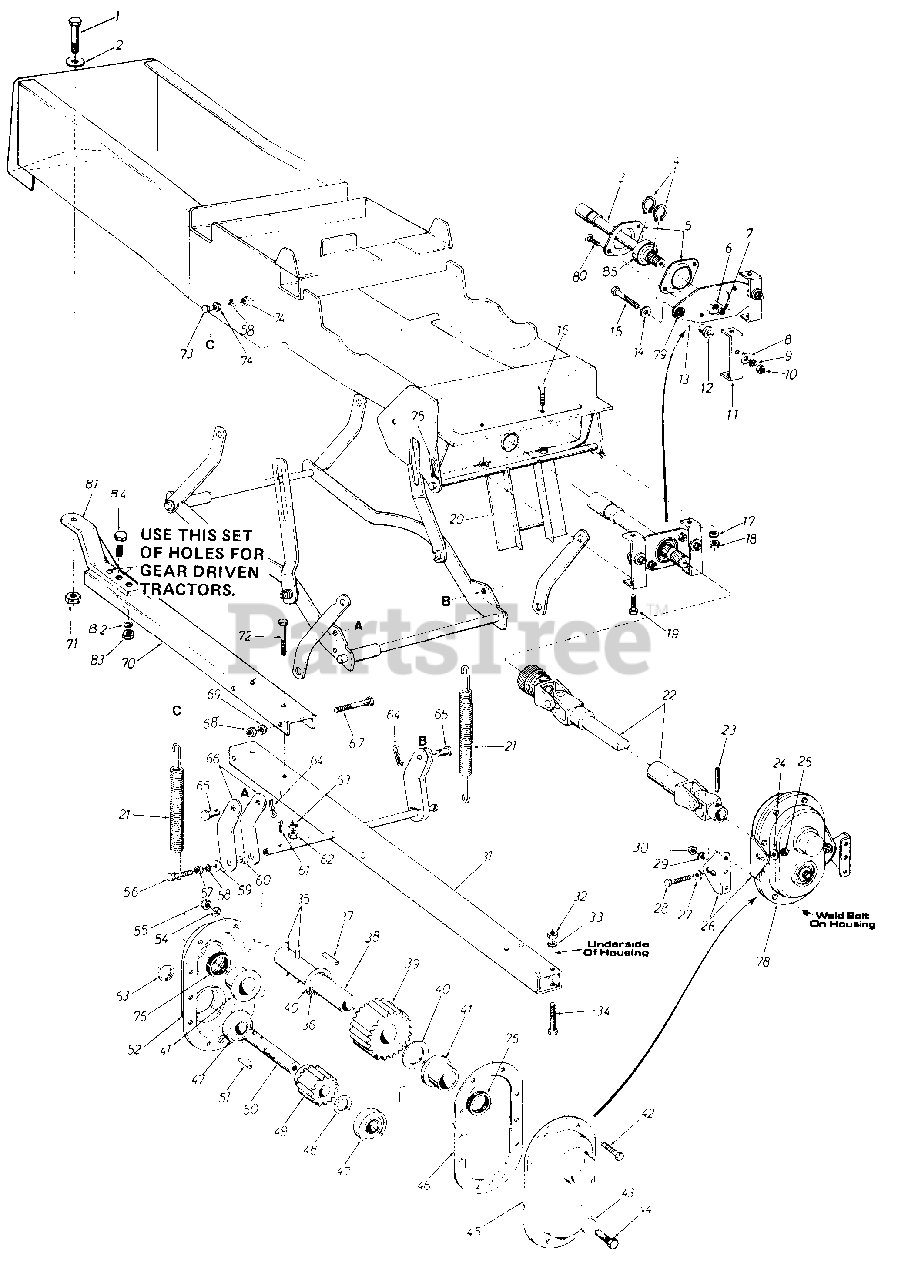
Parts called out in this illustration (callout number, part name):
1	Hex Scr. 5/8-18 x 1.31" Lg.
2	Fl.-Wash. .66" I.D. x 1.25" O.D. x .100
3	P.T.O. Shaft Extension Ass'y .
4	Retaining Riny 1.00" Dia. Shaft
5	Flangette Bearing
6	L.-Wash. 5/16" Scr.*
7	Hex Nut 5/16-18 Thd.*
8	Fl.-Wash. 3/8" I.D. x 1.00"O.D.
9	L Wash. 3/8" Scr.*
10	Hex Nut 3/8-24 Thd.*
11	P.T.O. Bearing Retaine Brkt.
12	Shoulder Spacer
13	P.T.O. Bearing Retainer Plate
14	Fl.-Wash. 3/8" I.D. x 1.00 O.D.
15	Hex Scr. 3/8-24 x 1.50" Lg.*
16	Hex Scr. 3/8-16 x .75" Lg.*
17	L.-Wash. 318" Scr.*
18	Hex Nut 3/8-16 Thd.*
19	Hex Scr. 3/8-16 x .75" Lg.*
20	Guide Bracket Ass'y.
21	Helper Spring .94 O.D. x 7.38" Lg.
22	Universal Drive Shaft Ass'y.
23	Spring Pin Spirol 5/16" x 2.50" Lg.
24	Belleville Wash. .341 I.D. x .88 O.D.
25	Hex Nut 5/16-18 Thd.*
26	Gear Box Support Bracket
27	Belleville Wash. .34 I.D. x .88 O.D.
28	Hex Scr. 5/16-18 x .75" L.g*
29	L.-Wash. 5/16" Scr.*
30	Hex Nut 5/16-18 Thd.*
31	Lift Shaft Ass'y.
32	Hex Ins. Jam L.-Nut 3/8-24 Thd.
33	L.-Wash. 3/8" Scr.*
34	Hex Scr. 3/8-24 x 2.75"Lg.*
35	Spring Pin Spirol 5/16" Dia. 1.75" Lg.
36	Snap Ring for 1.25" Dia. Shaft
37	Sq. Key 1/4" x 1.00" Lg.
38	Gear Shaft
39	28 Teeth Spur Gear
40	Fl.-Wash. 1.31" I.D. x 2.00"
41	Flange Bearing 1.25" I.D. 41.75" O.D.
42	Hex Screw 1/4-28 x .88 "Lg.
43	Fl.-Wash. .40" I.D. x 1.25" O.D. x .160
44	Hex L.-Scr. 3/8-24 x 1.00"Lg.
45	Complete Gear Housing Half-L.H.
46	Gasket
47	Ball Bearing 1.00" I.D. x 2.00" O.D.
48	Fl.-Wash. 1.03" I.D. x 1.63" O.D. x .090
49	15 Teeth Spur Gear
50	Input Shaft
51	Woodruff Key 1/4 x 3/4" Dia.
52	Complete Gear Housing Half-R.H.
53	Snap Ring for 1.00" Dia. Shaft
54	L.-Wash. 1/4" Scr.*
55	Hex Nut 1/4-28 Thd.
56	Hex Scr, 5/16-18 x 1.75"
57	Hex Nut 5/16-18 Thd.*
58	L.-Wash. 5/16" Scr.*
59	Fl.-Wash. .344 I.D. x 1.12 O.D. x .125
60	Spacer .81" I.D. x 1.00" O.D. x .31
61	Cotter Pin/32" Dia. x 1.00" Lg.*
62	Hex Ins.Jam L.-Nut 3/8-24 Thd.
63	L.-Wash. 3/8" Scr.*
64	Intern. Cotter Pin 1/2"Dia.
65	Clevis Pin .500" Dia.
66	Lift Bracket
67	Hex Scr. 3/8-24 x 4.50"Lg.*
68	Hex Ins. Jam L.-Nut 3/8-24 Thd.
69	L.-Wash. 3/8" Scr.*
70	Lift Bracket
71	Hex Ins. Jam L.-Nut 5/8-18 Thd.
72	Hex Scr. 3/8-24 x 2.75"Lg.*
73	Hex Scr. 5/16-18 x 1.75" Lg.*
74	Hex Nut 5/16-18 Thd.*
75	Intern. Cotter Pin 3/4" Dia.
76	Oil Seal 1.25" I.D. x 1.75" O.D. x .26
78	Gear Box Ass'y. Comp.
79	Rubber Grommet .50" I.D. I
80	Carriage Bolt 5/16-18 x .75 Lg
83	Hex Nut 1/2-13 Thd.
84	Hex Scr. 1/2-13 1-1/4 Lg.
85	Ball Bearing
